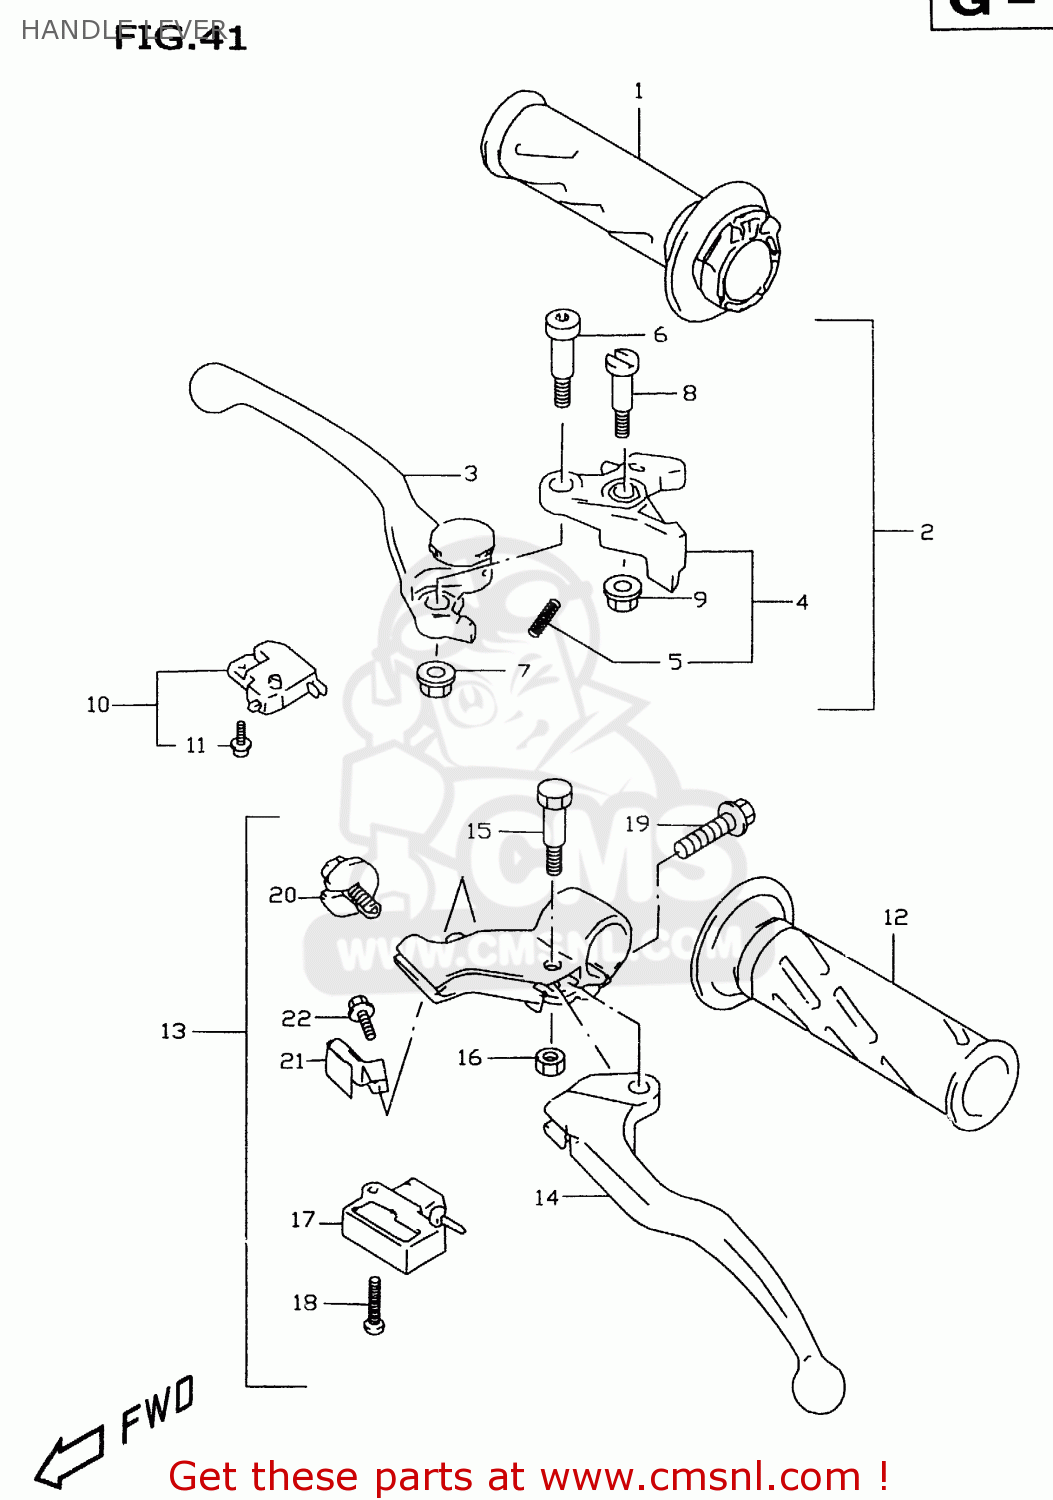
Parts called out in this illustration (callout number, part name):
1	GRIP,THROTTLE
2	LEVER ASSY,BRAKE
3	LEVER,ADJUST
4	KNOCKER
5	SPRING
6	BOLT,LEVER
7	NUT
8	BOLT,LEVER PIVOT
9	NUT
10	SWITCH ASSEMBLY,STOP
11	SCREW
12	GRIP,LEFT
13	LEVER ASSEMBLY,CLUTCH
14	LEVER,CLUTCH
15	BOLT,LEVER SET
16	NUT
17	SWITCH,CLUTCH
18	SCREW
19	SCREW
20	NUT,CABLE ADJUSTER
21	SPRING,ADJUST
22	SCREW,SPRING
